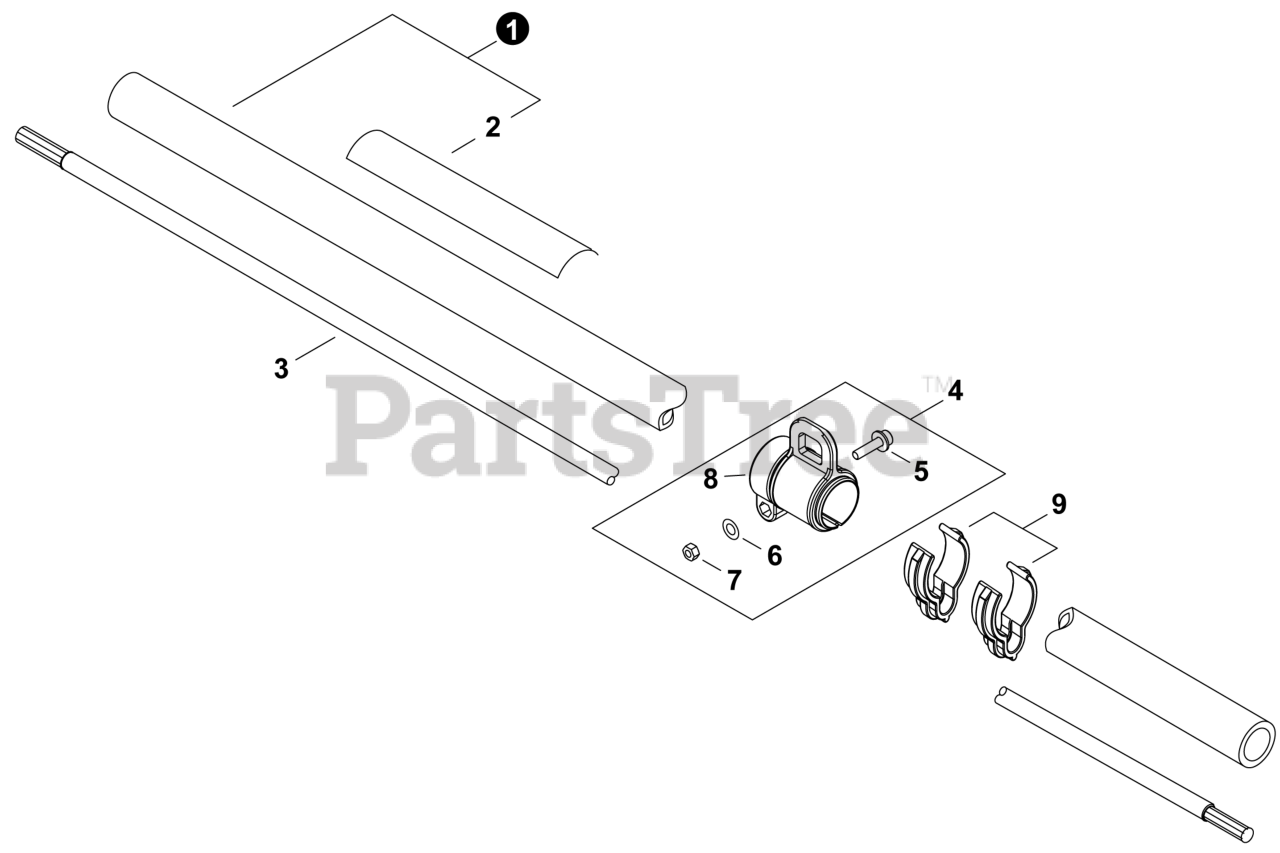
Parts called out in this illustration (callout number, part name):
1	MAIN PIPE ASSY
2	LABEL - CAUTION
3	DRIVESHAFT
4	HANGER ASSY, HARNESS
5	BOLT 5x20
6	WASHER 5
8	HANGER, HARNESS
9	CLIP, CABLE
